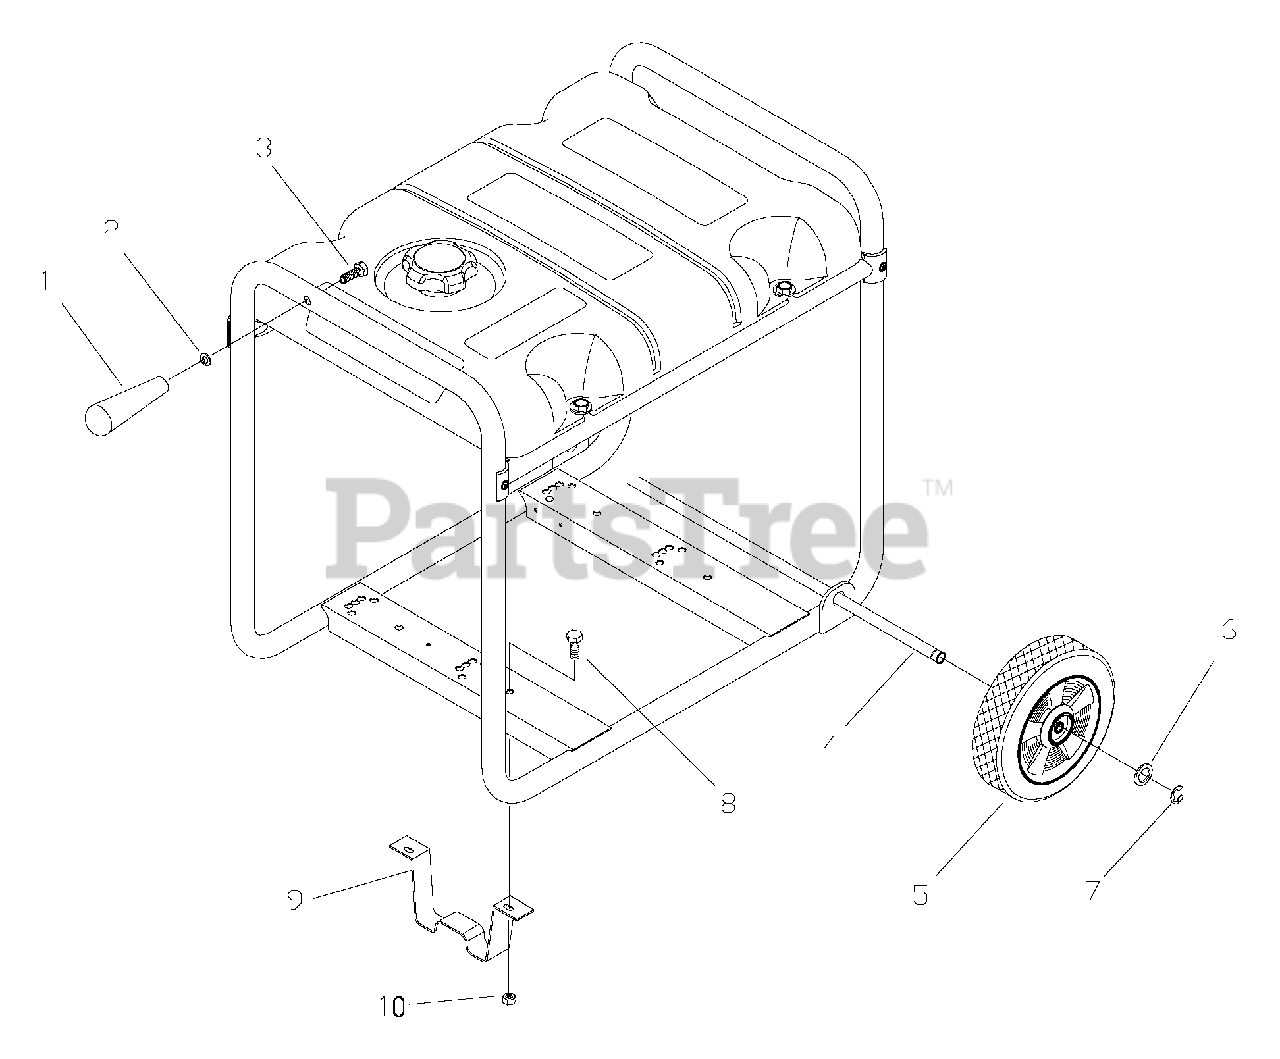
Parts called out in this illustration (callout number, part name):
2	WASHER, Lock, Split 3/8"
3	HHCS, 3/8 - 16 x 2
6	WASHER, 1/2"
7	E-RING
8	HHCS, M8 - 1.25 x 16
10	NUT, M8 Flange Serrated
